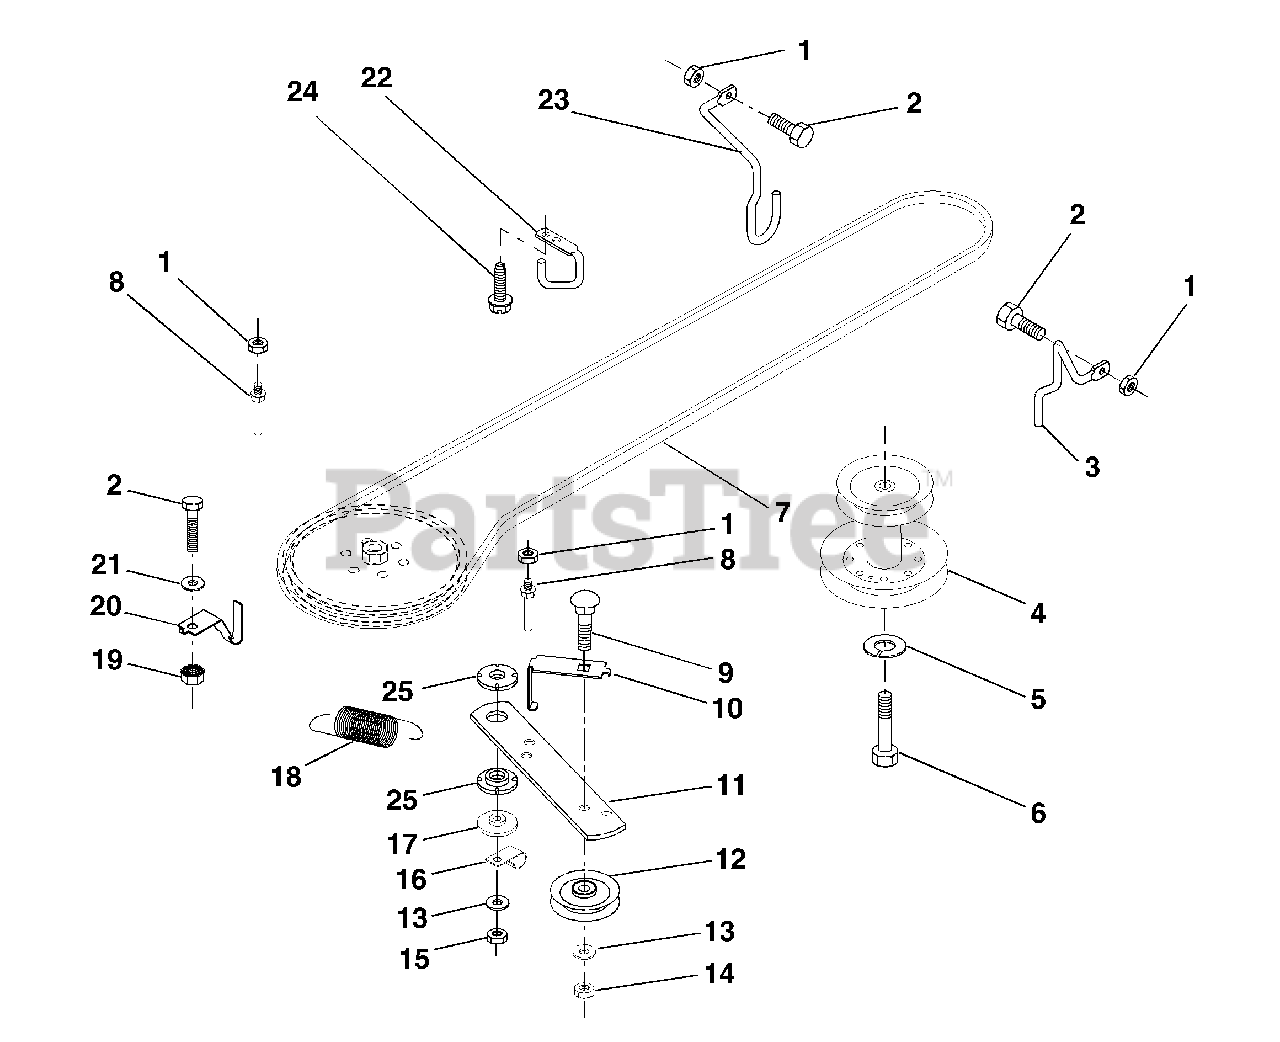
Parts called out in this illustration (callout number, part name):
1	Nut, Crownlock 5/16-18
2	Bolt, Hex Hd 5/16-18 UNC x 3/4
3	Keeper, Mower Drive, R. H.
4	Pulley, Engine
5	Washer, Lock 7/16
6	Bolt Hex 7/16-20 Gr. 5
7	Traction, V-Belt Drive
8	Keeper, T/A Ground Drive Belt
9	Bolt, Carr. 3/8-16 UNC x 1-1/2
10	Keeper, Belt Ground Drive Idler
11	Arm, Ground Drive Clutch
12	Idler, Flat
13	Washer 13/32 x 13/16 x 16 Ga.
14	Nut, Centerlock 3/8-16 UNC
15	Nut, Crownlock 3/8-16
16	Clip, Insulated
17	Spacer, Retainer
18	Spring Extension
19	Nut, Keps 5/16-18 UNC
20	Keeper, T/A Ground Drive Belt
21	Washer 11/32 x 5/8 x 16 Ga.
22	Keeper, Frame Ground Drive Belt
23	Keeper, Mower Drive, L. H.
24	Screw, Thd Cut 1/4-20 x 1/2
25	Bushing, Nylon
